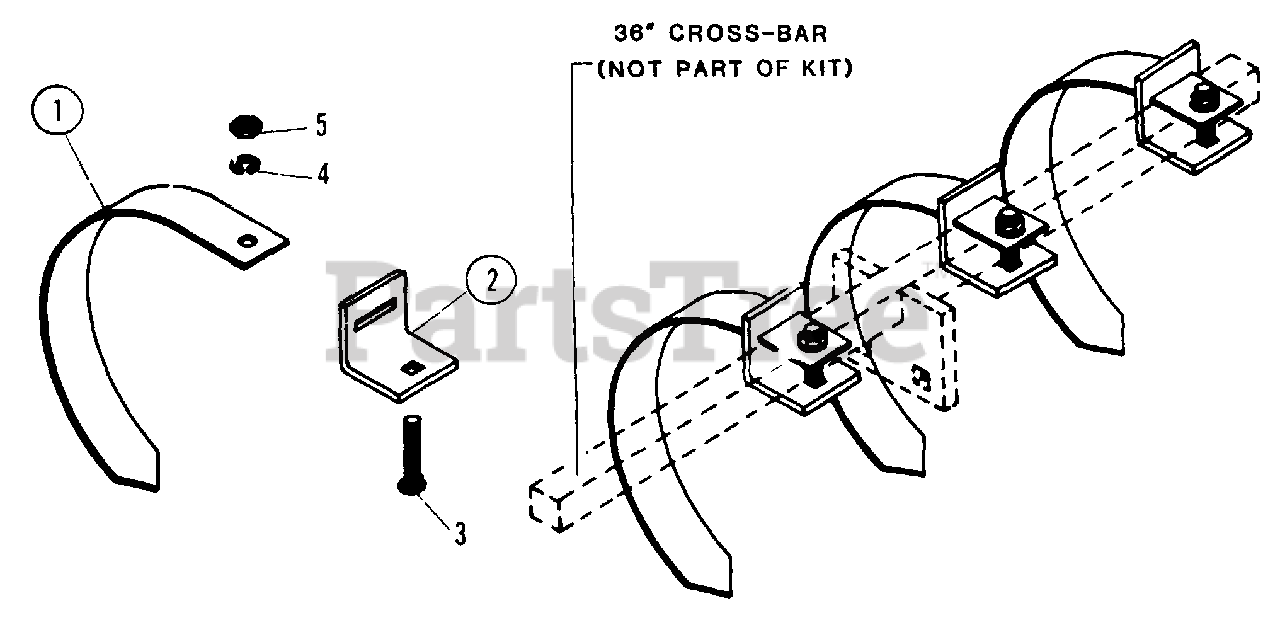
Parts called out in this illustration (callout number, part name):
1	SPRING-SHANK
2	CLAMP, SPRING
3	BOLT, 1/2 x 2-3/4 CARRIAGE
4	LOCKWASHER, 1/2"
5	NUT, 1/2 HEX
